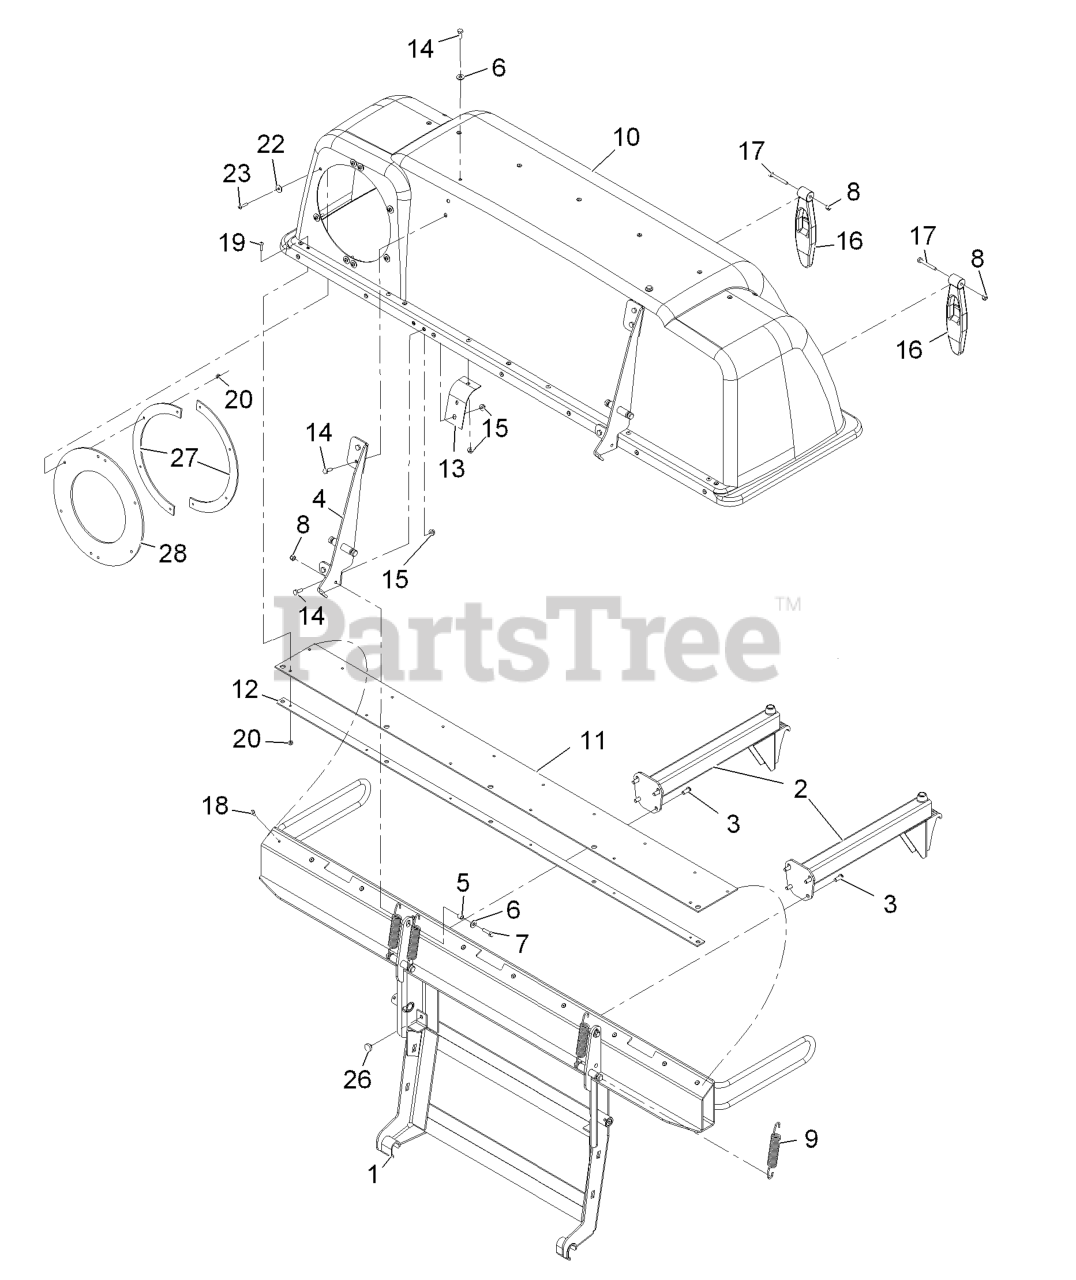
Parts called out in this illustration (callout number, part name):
1	FRAME-TRIPLE BAGGER
2	BAG SUPPORT ASM
3	SCREW-HSBH
6	WASHER-FLAT
7	SCREW-HH
8	NUT-LOCK, NI
9	SPRING-EXTENSION
10	ASM, HOOD
11	SEAL-HINGE
12	PLATE-BACKING
13	REINFORCEMENT-HOOD, BAGGE
14	SCREW-HH
17	SCREW-HH
18	RIVET-BLIND
19	SCREW-HEAD, TRUSS
20	NUT-LOCK, NI
22	WASHER-FLAT
23	SCREW-PPH
27	CLAMP-SEAL
28	SEAL-TUBE
